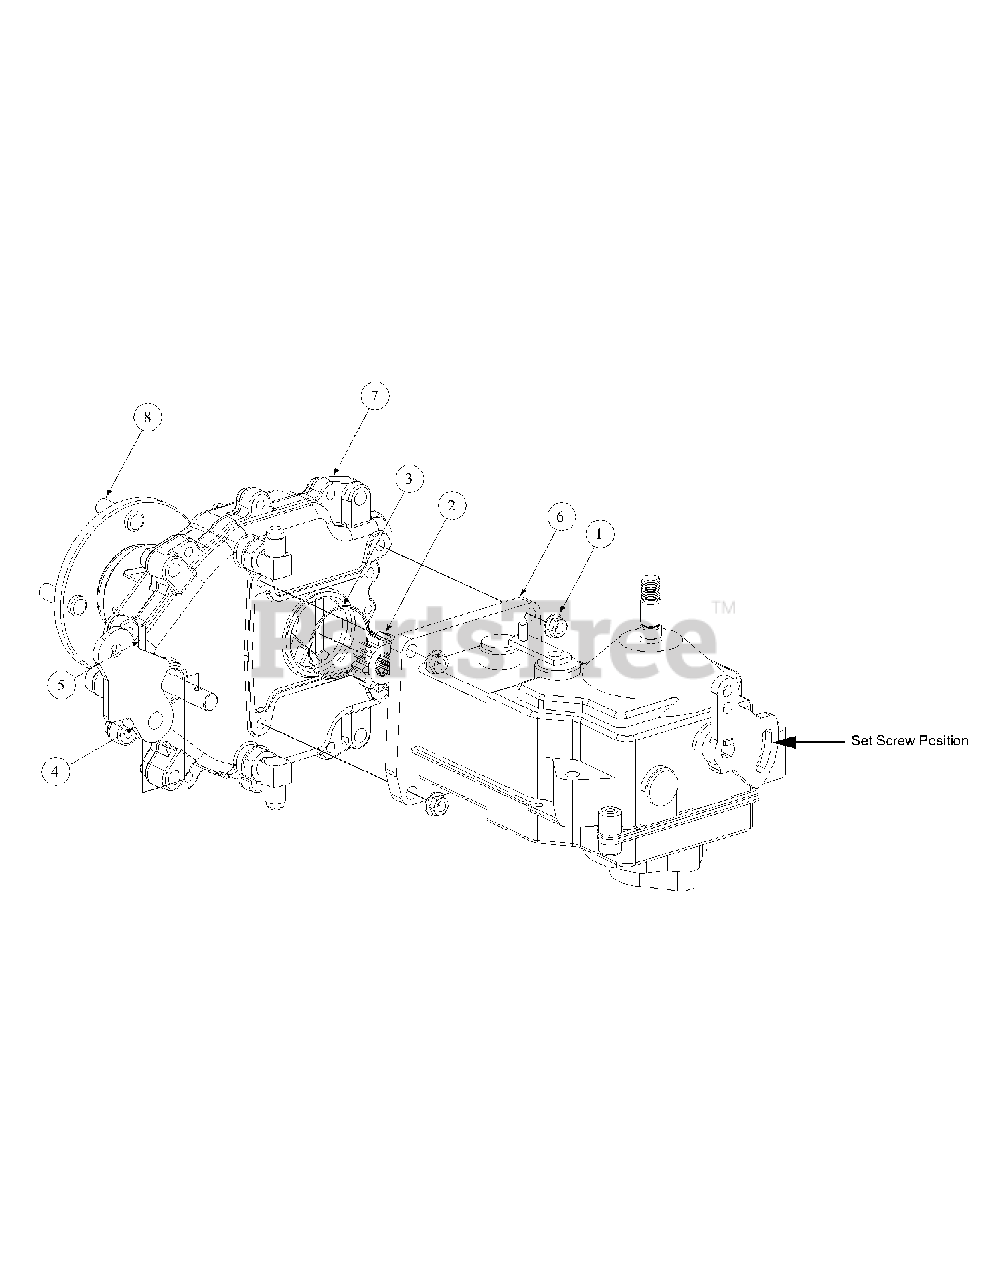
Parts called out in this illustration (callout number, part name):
1	Lock Nut, Hex Flange 5/16-18
2	Gear, Spur, 14T
3	O-Ring, 2.00 x .070
4	Parking Brake Lever
5	Pin, Spirol, 3/16 x 1.25 HD
7	Transmission Assembly
8	Rib Neck Stud, 1/2-20
9	Set Screw, 5/16 - 24 x 1.25
